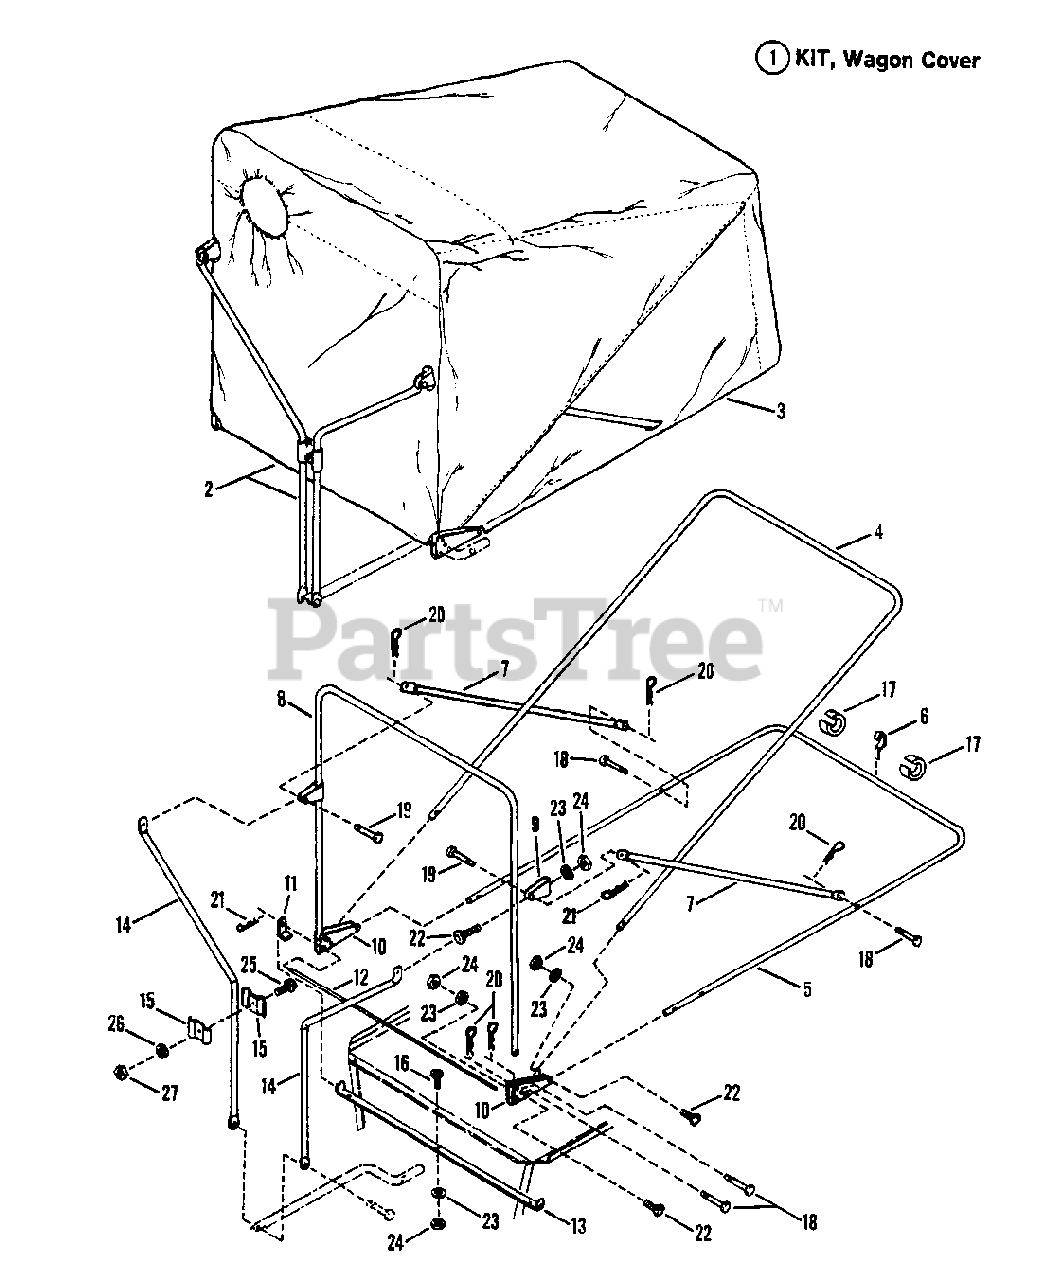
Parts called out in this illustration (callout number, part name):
1	KIT, Bag-N-Wagon Cover
2	ASSEMBLY, Frame & Canopy
3	CANOPY, Cloth Only (CHARCOAL); (12396, White)
4	FRAME, Center
5	FRAME, Base
6	LOCK, Canopy
7	BRACE, Frame
8	FRAME, Front
9	CLAMP, Rod
10	BRACKET, Corner
11	CLIP, Hinge
12	PIN, Hinge
13	MOUNT, Hinge
14	STRUT, Frame
15	CLAMP, Strut
16	BOLT, 1/4-20 x 3/4" Short Neck Carriage, Grade 5
17	RING, Plastic Wear
18	PIN, 1/4 x 1-1/8" Clevis
19	PIN, 5/16 x 1-11/16" Clevis
20	HAIRPIN, 1/4"
21	HAIRPIN, 3/32 x 1-19/32"
22	BOLT, 1/4-20 1" Square Neck Carriage, Grade 2
23	WASHER, 1/4" Internal Tooth Lock
24	NUT, 1/4-20 Hex
25	SCREW, 3/8-24 x 1" Hex Head Cap, Grade 5
26	WASHER, 3/8" Split Lock
27	NUT, 3/8-24 Hex, Grade 2
